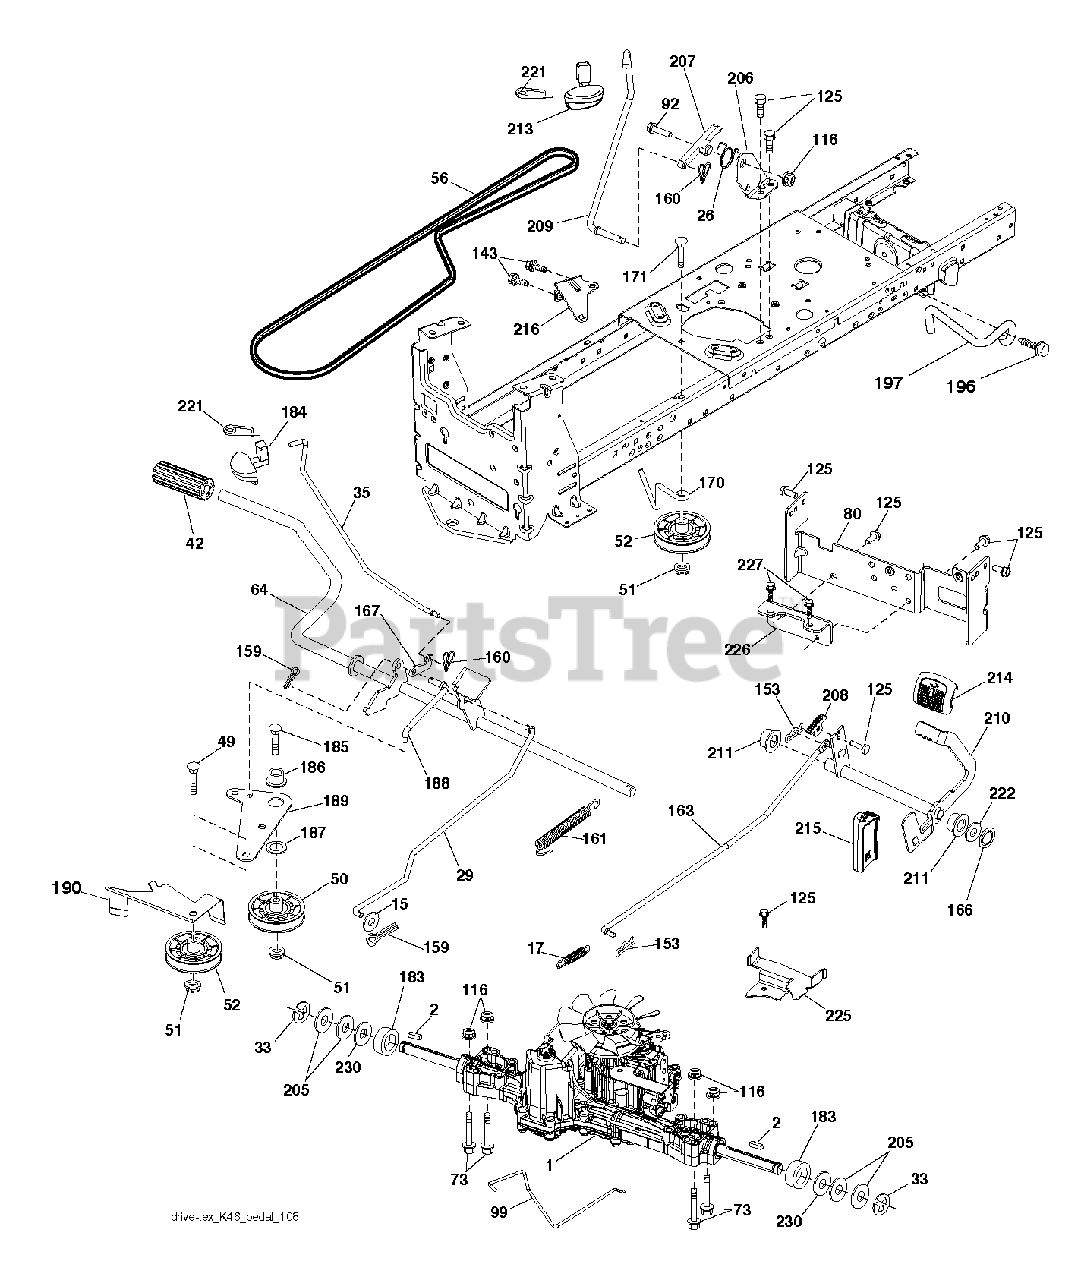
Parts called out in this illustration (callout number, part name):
2	SQUARE KEY
15	WASHER
17	SPRING, BREAK
26	SPRING.RETURN.CRUISE
29	ROD.BRAKE.K46
33	E-RING LT
35	ROD.BRKAE.PARKING.STEALTH
42	PEDAL COVER T
50	IDLER.FLAT.910.OFFSET
52	IDLER.V-GROOVE.910.OFFSET
64	SHAFT.ASM.PEDAL.BRK.CN
99	ROD.SPRING.BYPASS.K46.LT.Z
116	NUT LOCK HEX FLANGE 5/16-18
125	SCREW
143	SCREW LT
159	COTTER PIN
160	RETAINER CLIP
161	SPRING, RETURN LT
163	ROD.CONTROL.PEDAL.K46
166	NUT.PUSH.625
167	LATCH BRAKE PARKING
170	KEEPER.V-IDLER.CENTER.
183	SPACER AXLE
186	SPACER.RETAINER
188	LINK.CLUTCH.GROUND DRI
189	BELLCRANK.GRDDRIVE.NST
190	KEEPER.BELLCRANK.DRIVE
196	SCREW 3/8-16X1
197	LINK.CLUTCH.ANIT-ROTAT
206	BRKT.MOUNT.LATCH.CRUIS
207	LATCH.CONTROL.CRUISE
208	GEAR.SECTOR.CONTROL.CR
209	ROD.CONTROL.CRUISE.STE
210	ROCKER.ASM.PEDAL.CONTR
211	BEARING RER
213	KNOB.CONTROL.CRUISE
214	PAD PEDAL FORWARD
215	PEDAL.REVERSE.TEX.GT.4
216	BRKT.PULLEY.IDLER.WTEX
221	RETAINER.SPRING.CLIP.H
222	WASHER 21/32 X 1-1/4 X 10 GA.
225	KEEPER.BELT.TRANSAXLE.
226	BRACKET MOUNT TORQUE
